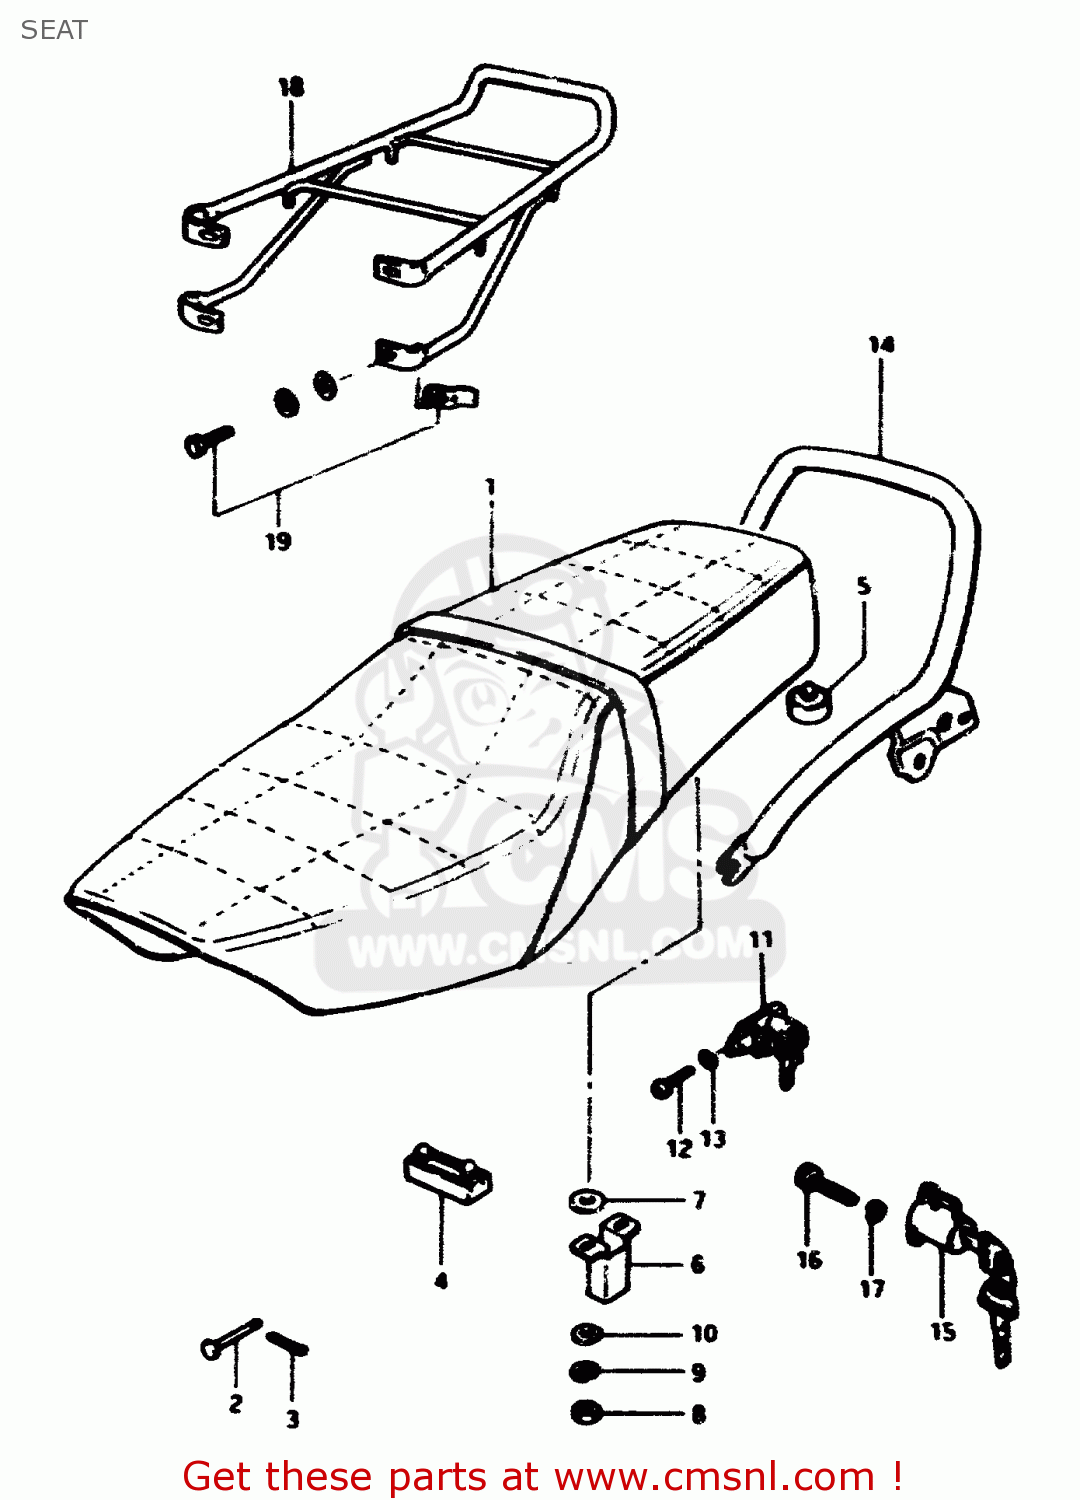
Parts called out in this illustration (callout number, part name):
1	SEAT ASSY (BLACK)
2	PIN
3	PIN
4	CUSHION
5	CUSHION
6	PLATE,CLAMP GUIDE
7	WASHER(8.5X18X1)
8	NUT
9	LOCK WASHER
10	WASHER
11	LOCK ASSY,SEAT
12	SCREW
13	LOCK WASHER
14	HANDLE, PILLION RIDER
15	LOCK ASSEMBLY,HELMET
16	BOLT 6X11
17	LOCK WASHER
18	CARRIER, SPORT
19	FITTING SET,CARRIER
